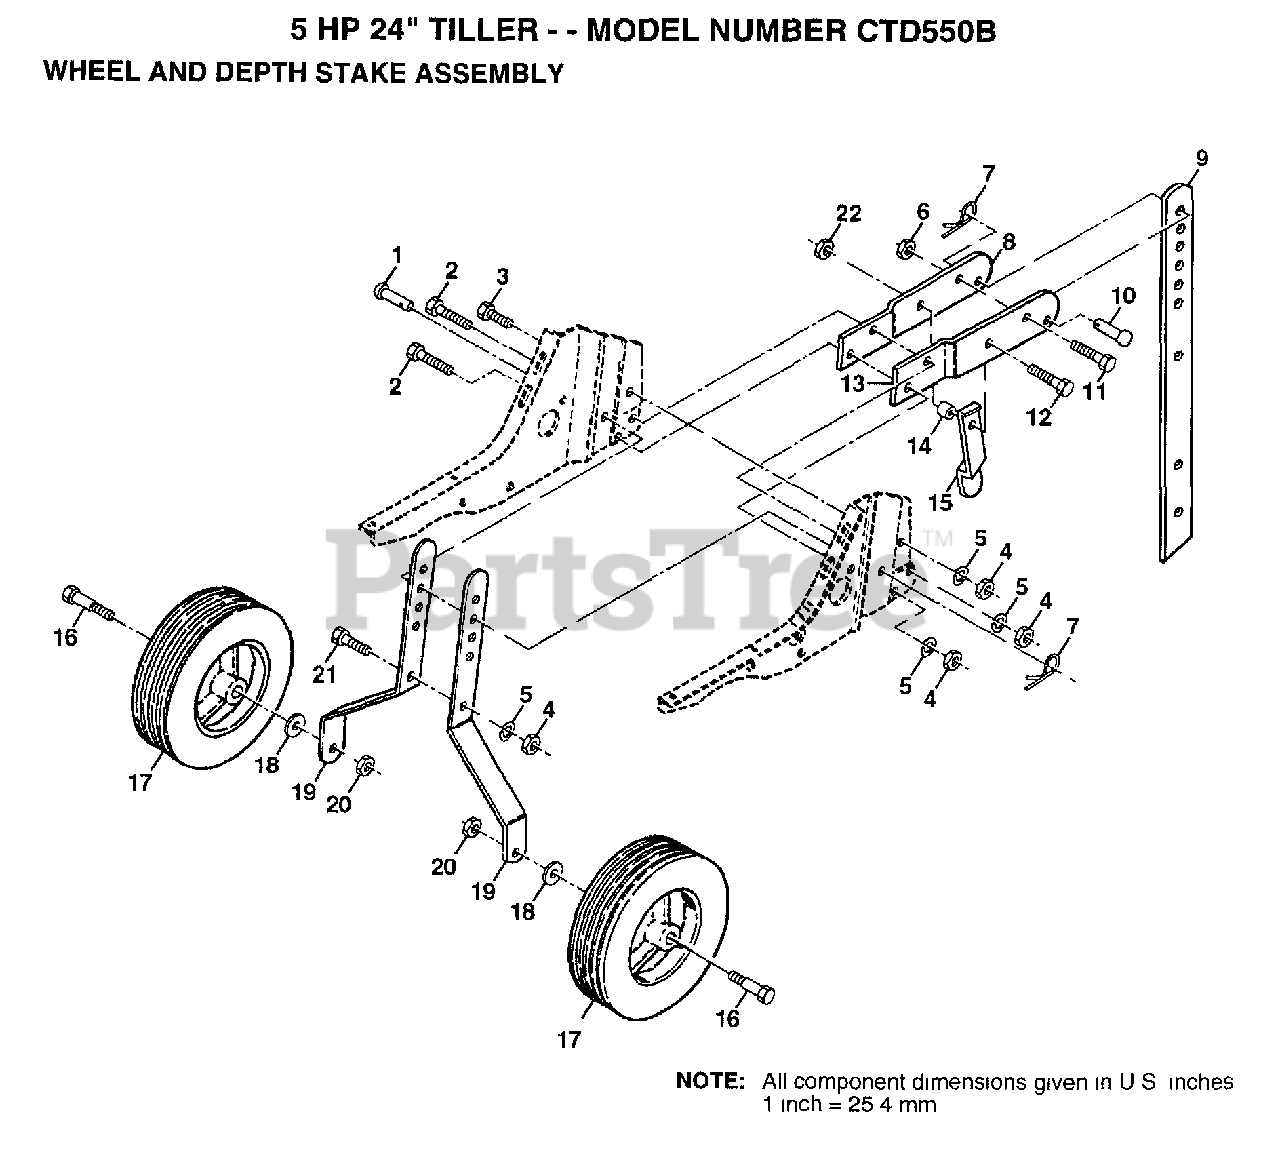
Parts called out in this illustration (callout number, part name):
1	DRILLED RIVET RT
3	BOLT
4	NUT.HEX.5/16-18
5	LOCKWASHER
6	NUT
7	SPRING.RETAINER
8	SUPPORT STAKE RH
11	BOLT
12	BOLT.HEX.5/16-1.5
13	SUPPORT STAKE LH
14	WASHER
15	STAKE SPRING TI
16	BOLT SHOULDER
18	WASHER
19	BRACKET.WHL.PNT.
22	NUT
